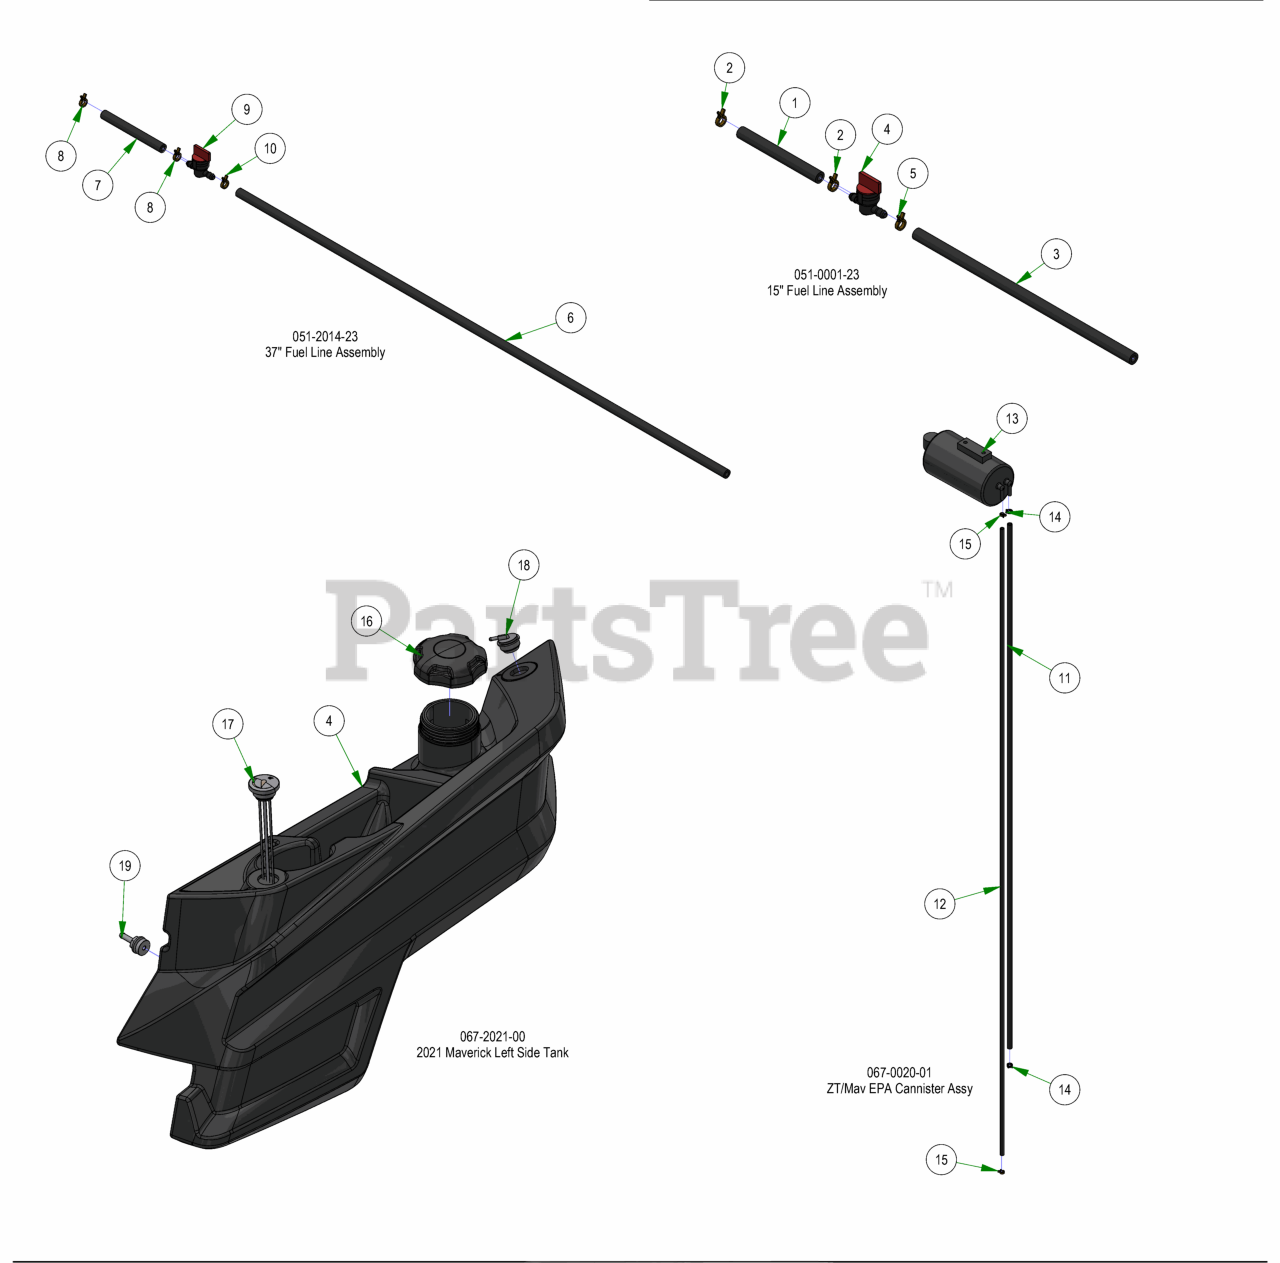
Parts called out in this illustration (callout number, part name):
1	1/4 Fuel Line
2	1/4 Fuel Hose Clamp
3	1/4 Fuel Line
4	2 Way Fuel Shut-Off Valve
5	1/4 Fuel Hose Clamp
6	33" 1/4 Fuel Line
7	1/4 Fuel Line
8	1/4 Fuel Hose Clamp
9	2 Way Fuel Shut-Off Valve
10	1/4 Fuel Hose Clamp
11	1/4" Vinyl Tubing, 46" Long
12	3/16" Vinyl Tubing, 55" Long
13	Carbon Canister
14	MZ Tank Hose Clamp 1/4 Vinyl
15	3/16" Vinyl Hose Clamp
17	Fuel Gauge w/Grommet
18	Rollover Valve W/Grommet
19	Fuel Pick-up for 067-2021-00
